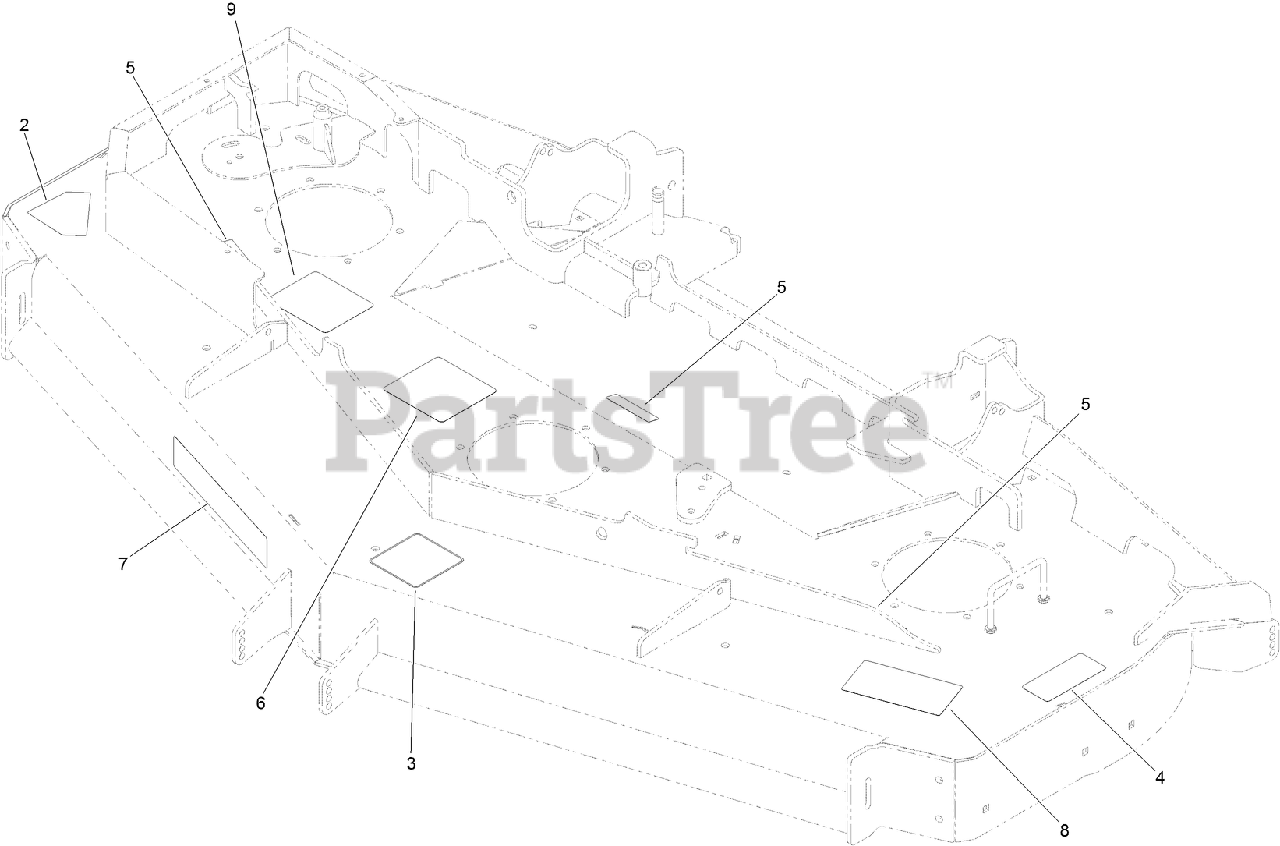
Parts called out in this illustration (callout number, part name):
2	DECAL-DANGER
3	Decal, Anti-Scalp
4	DECAL-TORQUE
5	DECAL-COVER, MISSING
6	DECAL-ROUTING, DECK BELT
8	DECAL-DANGER, THROWN OBJECT
9	DECAL-SPINDLE, COUNTER ROTATING
